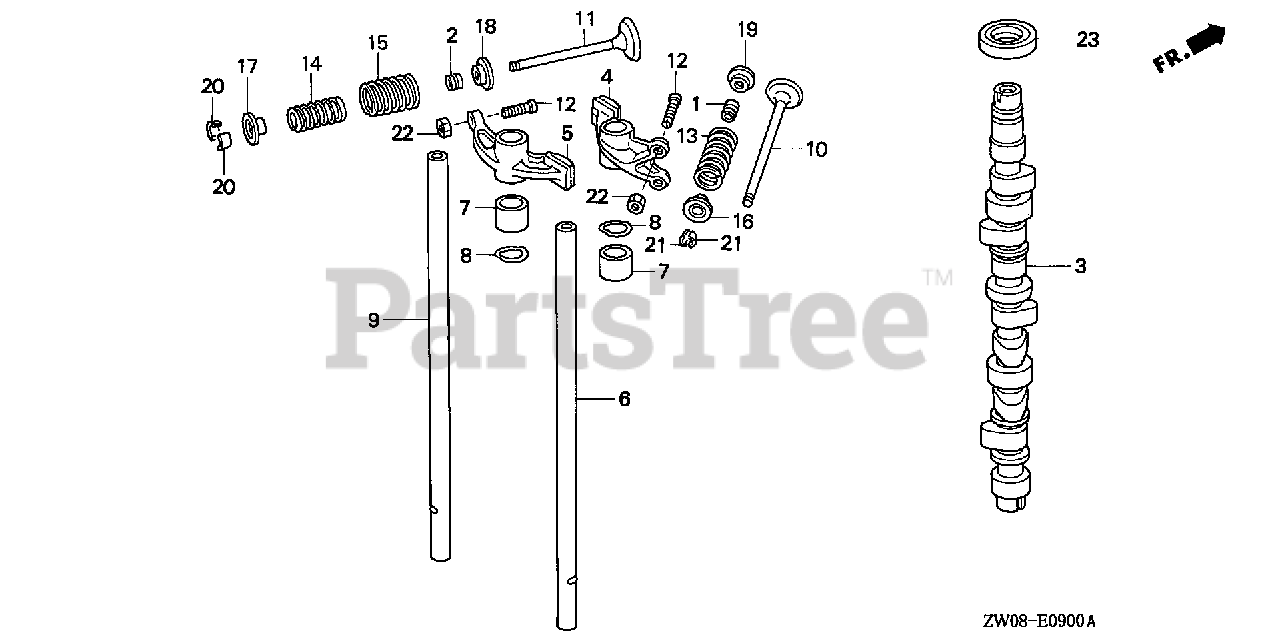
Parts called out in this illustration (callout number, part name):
1	SEAL, VALVE STEM (NOK)
2	SEAL, VALVE STEM (NOK)
4	ARM ASSY., IN. ROCKER
5	ARM, EX. ROCKER
6	SHAFT, IN. ROCKER ARM
7	COLLAR, ROCKER
8	WASHER, WAVE
9	SHAFT, EX. ROCKER ARM
10	VALVE, IN.
11	VALVE, EX.
12	SCREW, TAPPET ADJUSTING
13	SPRING, IN. VALVE
14	SPRING, EX. VALVE (INNER)
15	SPRING, EX. VALVE (OUTER)
16	RETAINER, VALVE SPRING
17	RETAINER, VALVE SPRING
18	SEAT, VALVE SPRING
19	SEAT, VALVE SPRING
20	COTTER, VALVE
21	COTTER, VALVE (FUJI VALVE)
22	NUT, TAPPET ADJUSTING
23	OIL SEAL (31X46X7)
